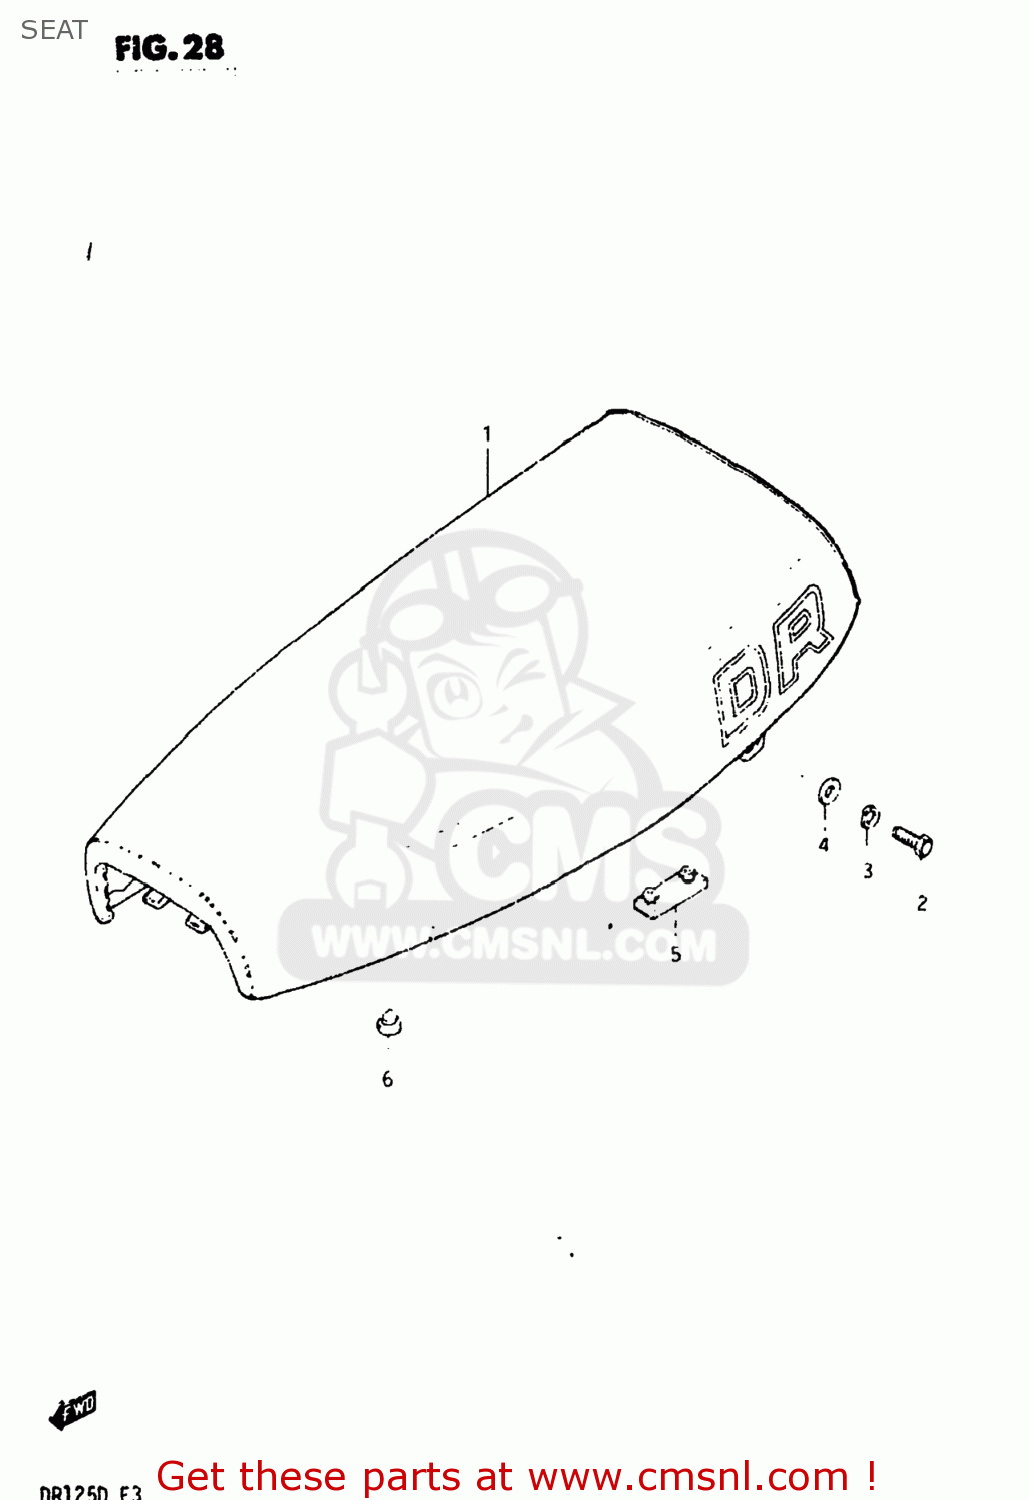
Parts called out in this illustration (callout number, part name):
1	SEAT ASSEMBLY
2	BOLT
3	LOCK WASHER
4	WASHER
5	CUSHION
6	CUSHION
